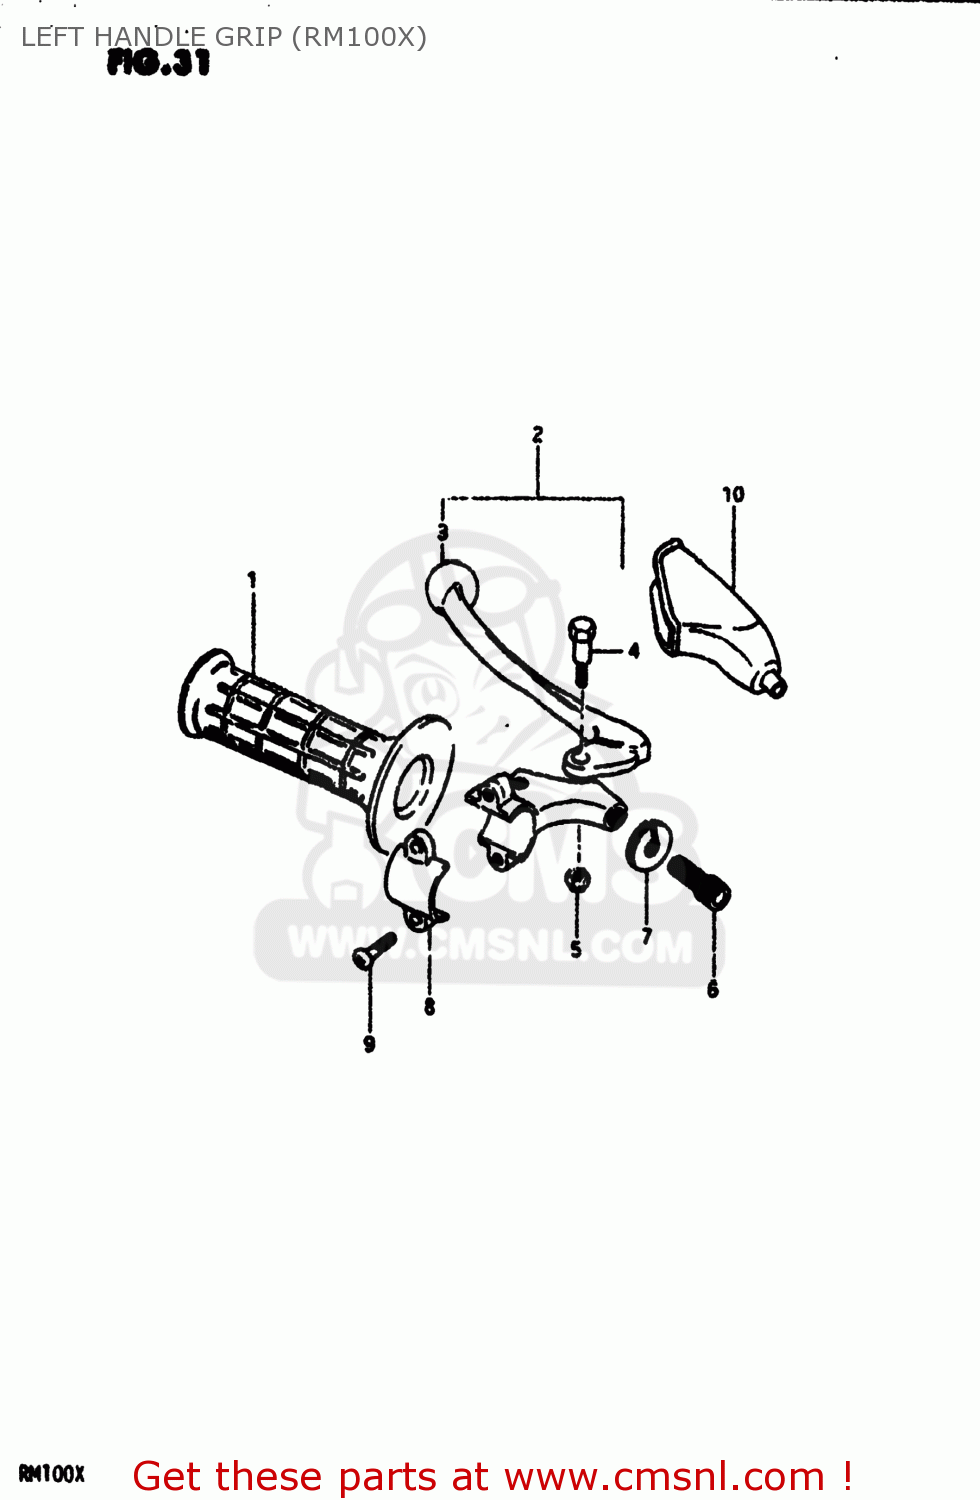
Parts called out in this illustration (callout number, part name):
1	GRIP,LEFT
2	LEVER ASSEMBLY
3	LEVER,CLUTCH
4	BOLT,LEVER
5	NUT 6MM
6	ADJUSTER,CABLE
7	NUT,CABLE ADJUSTER
8	BRACKET,LEVER
9	SCREW
10	COVER,CLUTCH LEVER
